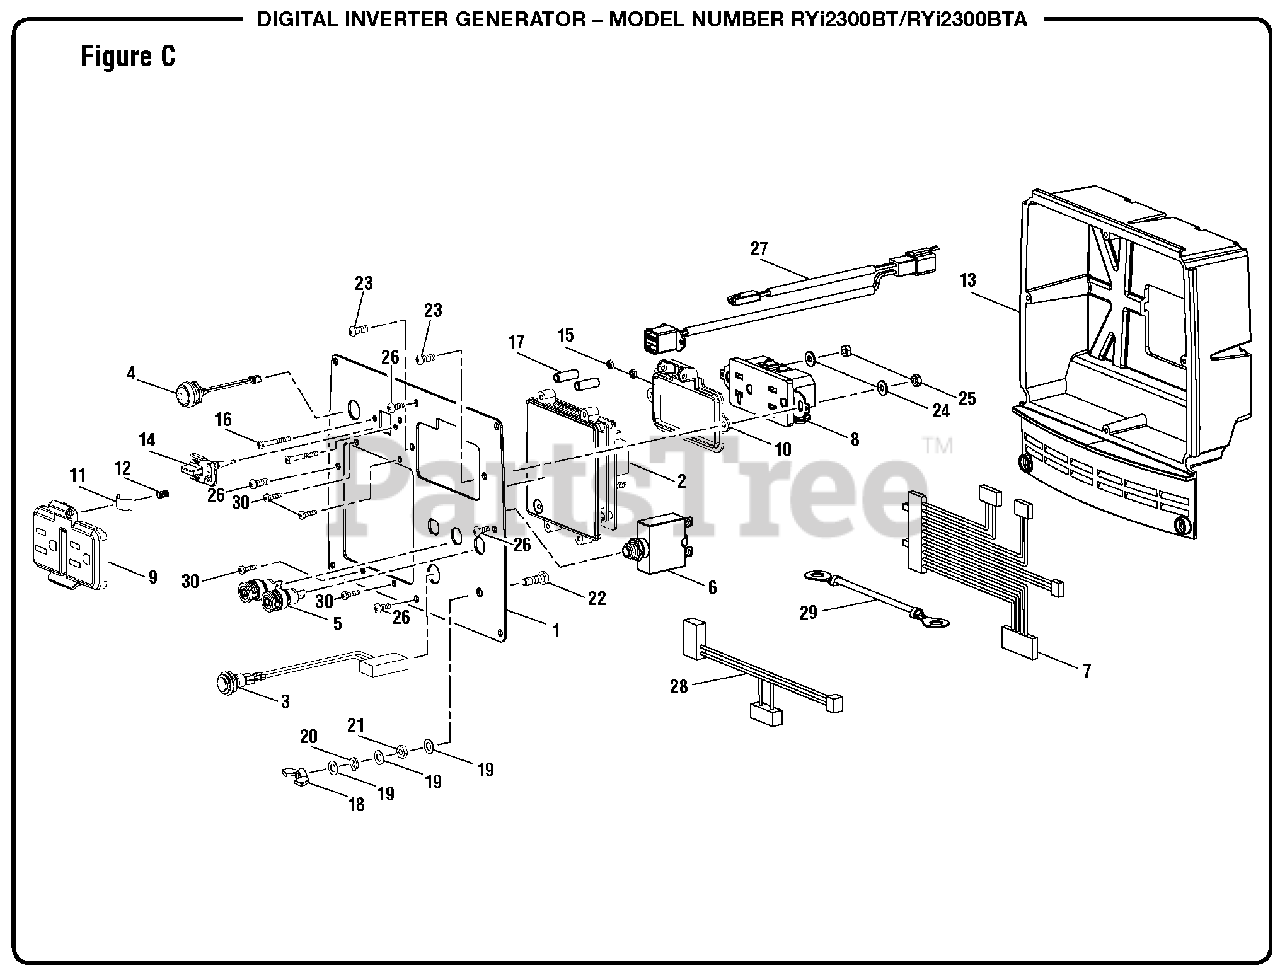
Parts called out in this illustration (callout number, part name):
1	Faceplate
2	GENControl(TM) Display Assembly
3	Overload Reset Button
4	Auto Idle Button
5	Connector (Black)
6	Circuit Breaker (20A)
7	Wire Harness (GENControl(TM) Display)
8	120 Volt Duplex Receptacle (20 Amp)
9	Movable Outlet Cover
10	Fixed Outlet Cover
12	Compression Spring
13	Electrical Panel Housing
14	Dual USB Cover
16	Screw (M3)
17	Spacer (17.2 mm)
18	Wing Nut (M5)
19	Washer (ID5.3 x OD10 x 0.5t)
20	Lock Washer (ID5 x OD9 x 1.3t)
21	Hex Nut (M5)
22	Bolt (M5 x 16 mm, Pan Hd.)
23	Bolt (M4 x 10 mm, T15 Torx Drive Hd.)
24	Flat Washer (ID4.2 x OD10)
25	Hex Nut (M4)
26	Screw (#6-20 x 3/8 in., T15 Torx Pan Hd.)
27	Regulator Wire Harness w/ USB Ports
28	Internal Wire Assembly
29	Ground Wire
30	Screw (M3.1 x 10 mm, Torx Hd.)
